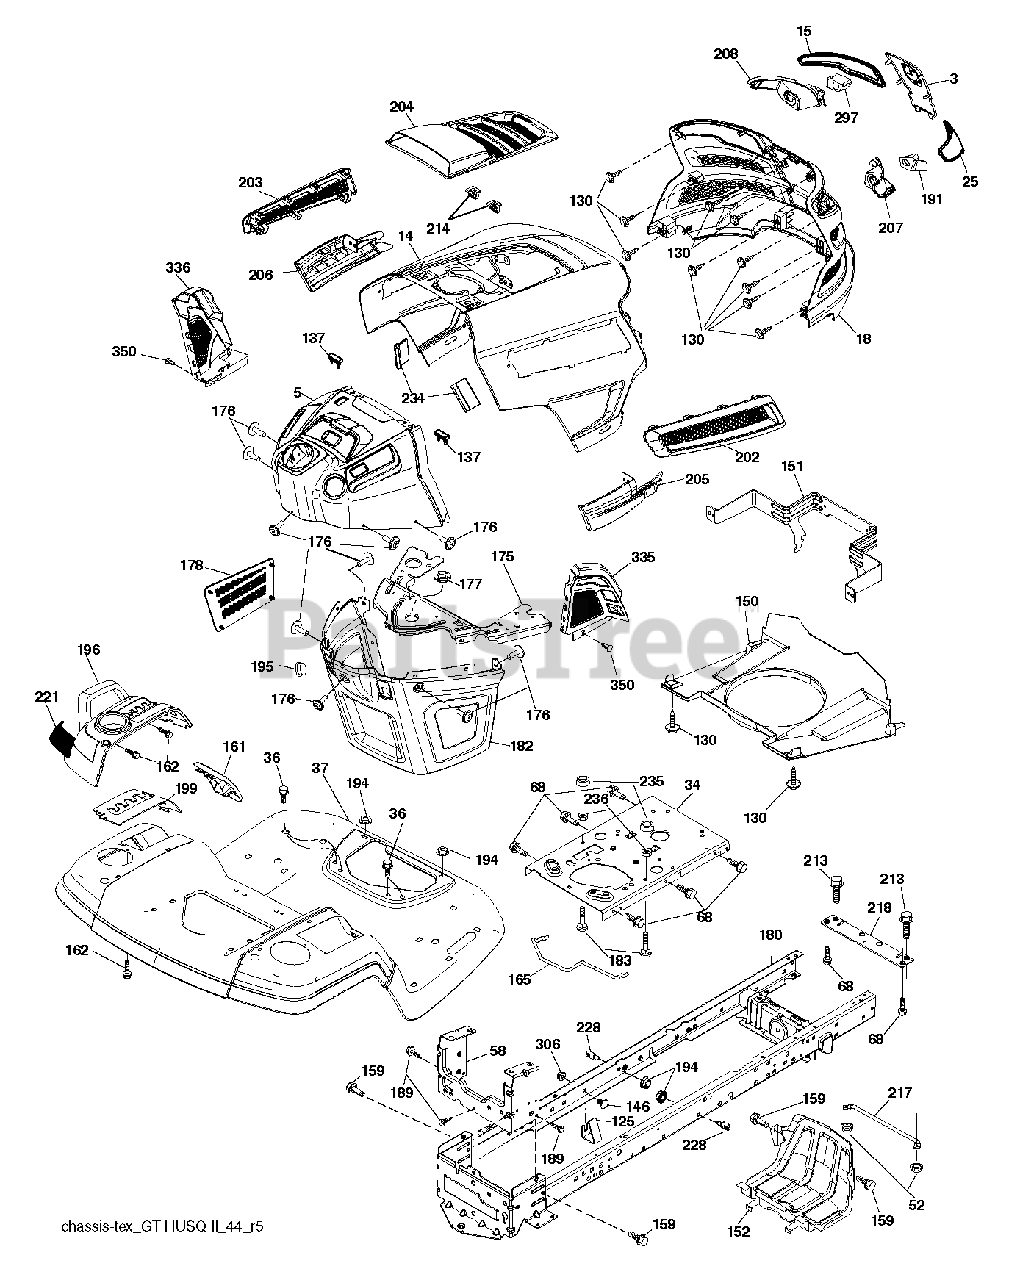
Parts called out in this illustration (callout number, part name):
3	APPLIQUE.SUBASM.GT.HUSQ.II
5	GT2.DASH.UPPER.W/BUMPERS
14	HOOD.ASM.HUSQVARNA.GT.TEX.ORAN
15	LENS.HEADLIGHT.LH.GTII.2011
18	GRILLE.SUBSTRATE.2011.
25	LENS.HEADLIGHT.RH.GTII.2011
34	PLATE.ENGINE.WELDED.CHASSIS
36	SCREW 5/16"
37	FENDER.PNT.TX.GT.CH/FW/DL.HUSQ
52	LOCKNUT
58	DRAWBAR.UPPER.2PC,LRG.FENDER
68	SCREW LT
125	CLIP.FUEL.LINE
130	SCREW.#10 X 0.750.BOS
137	BUMPER DASH
146	BOLT.RDHD.SHT.SQNK.3/8-16X5/8
150	AIR.DUCT.GTV.BLACK
151	BRACKET.PIVOT.HOOD.GT.HUSQ.II
152	SHIELD.BROWNING.PNT.GT.V2
159	SCREW, 3/8-16X3/4
161	CONSOLE.WINDOW.FUEL.HUSQ.GT
162	SCREW.HI-LO.CONSOLE
165	SUPPORT.TANK.REAR.W/TEX
175	PLATE.CROSSMEMBER.HUSQ
176	SCREW.#10-24X5/8.RN.QU
177	BUSHING STEERING
178	CARGO.ASM.NET.TXGT.W/C
180	CHASS.WLDMNT.TLT.12GA/2PC.20"
182	DASH.LOWER.COMMON.12V.ADAPTOR
183	BOLT.5/16-18X1-1/4 FULL THD
189	SCREW
191	INSERT.REFLECTIVE.RH.HUSQ.GTII
194	NUT LOCK HEX FLANGE 5/16-18
195	PLUG.HOLE.DASH.LOWER.12V.BLK
196	SUBASM.CONSOLE.HUSQ.GT.DECKLFT
199	PLATE.DECK.LIFT.HUSQVARNA.GT
202	VENT.SIDE.RH.GT.HUSQ.II.
203	VENT.SIDE.LH.GT.HUSQ.II.498
204	VENT.TOP.HUSQ.GT2
205	SIDE.TRIM.RH.GT.HUSQ.II
206	SIDE.TRIM.LH.GT.HUSQ.II.GRAY
207	BEZEL LIGHT.RH.GT.II.MYLAR
208	BEZEL LIGHT.LH.GT.II.MYLAR
213	BOLT
214	CLIP.RETAINER.TINNER.
217	ROD.PIVOT.HOOD
218	X-PIECE.HOOD.STOP.NON/
221	REFLECTOR.LH.TEX GT HU
228	STUD.FASTNER.W/ANTI-ROTATE
234	BUMPER.HOOD.TEX.HUSQVARNA
235	SPACER FENDER
236	NUT.CENTERLOCK.5/16-
297	INSERT.REFLECTIVE.LH.HUSQ.GTII
306	NUT LOCK FLG 3/8-16 UNC
335	COVER.LOWER.DASH.RH.BLACK
336	COVER-LH.LOWER.DASH.GT2.BLACK
350	CLIP.X-MAS.TREE
